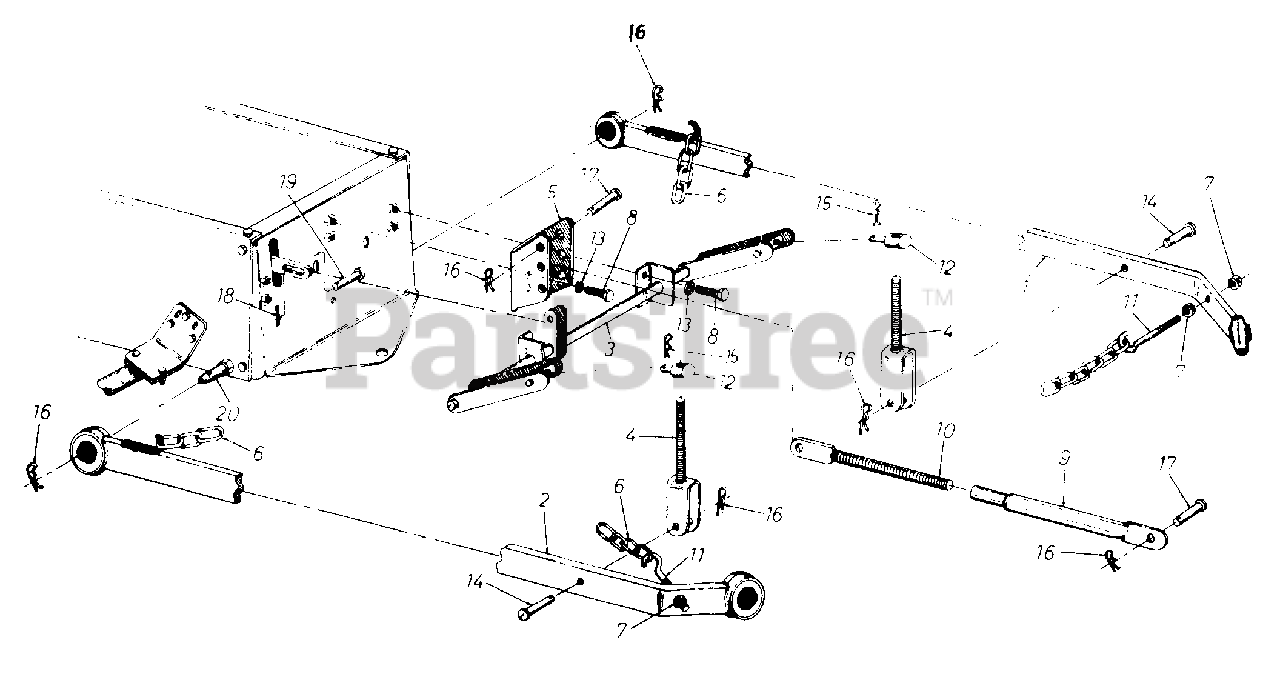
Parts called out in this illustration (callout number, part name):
1	Draft Bar Assembly-R.H.
2	Draft Bar Assembly-L.H.
6	Chain 20 links
7	Hex Cent. L.-Nut 7/16-14 Thd.
8	Hex Bolt 5-3/8-16 x 1 Lg. Grade 5
10	Clevis Screw
11	Hitch Chain Hook
12	Clevis Pin
13	L.-Wash . 3/8 " I. D.
14	Clevis Pin 5/8 Dia. x 1.66 Lg.
15	Hairpin
16	Hairpin
17	Clevis Pin 5/8 Dia. x 2.4 Lg.
18	Cotter Pin 1/8 Dia. x 1-1/4 Lg.
19	Clevis Pin
20	Link Clevis Pin
